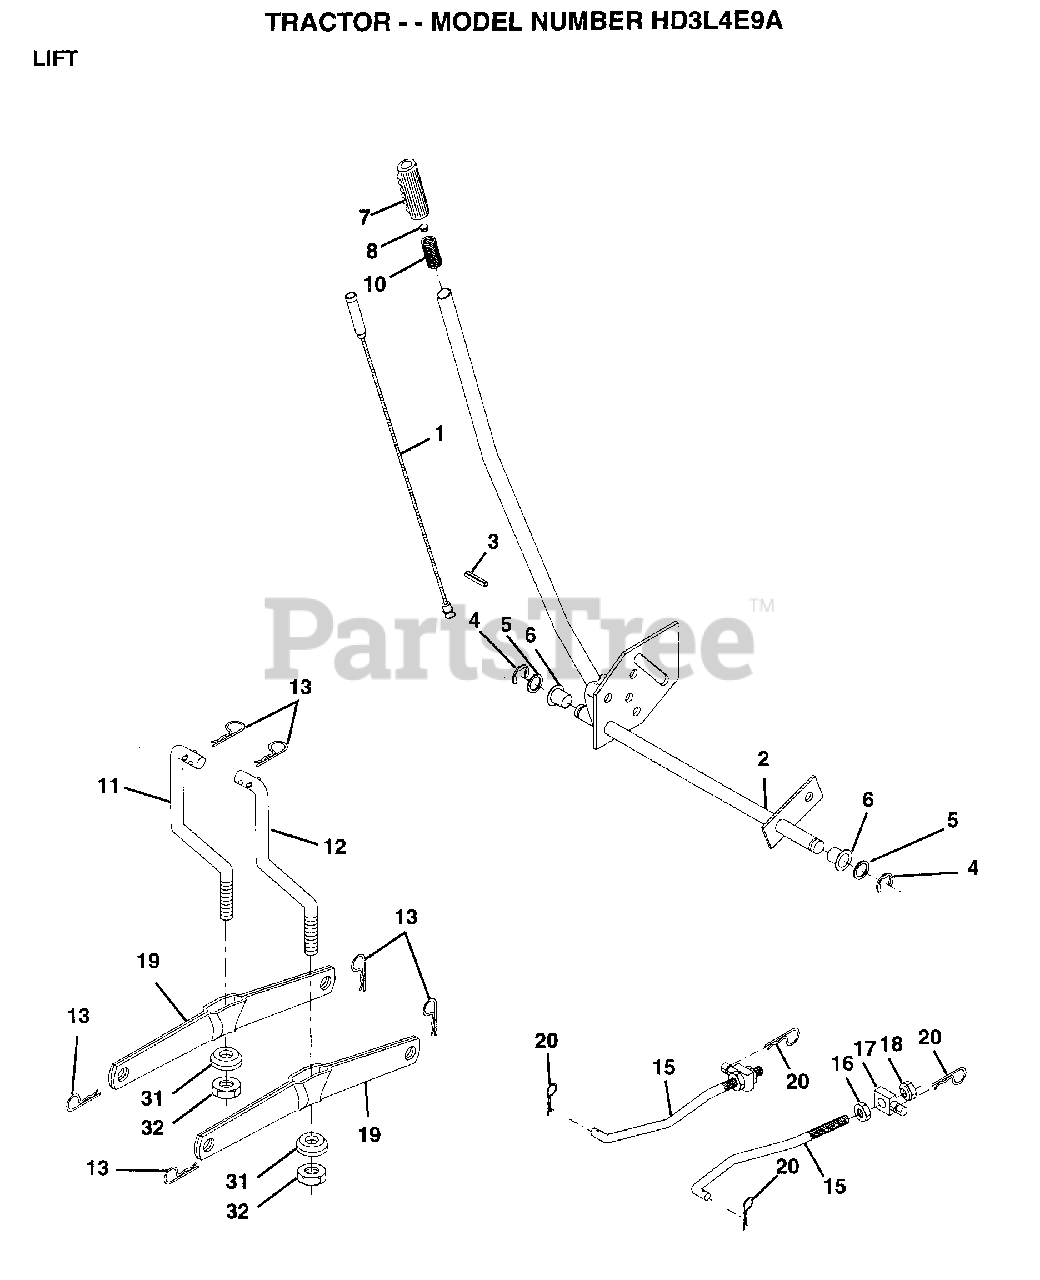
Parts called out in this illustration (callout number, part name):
1	WIRE ASM
2	HANDLE.LIFT.LH.
3	PIN GROOVE
5	WASHER
6	NYLON BEARING
7	CAP T
15	LINK.FRONT
16	NUT
17	TRUNION
18	NUT.LK.W/WSH.1/2.
19	ARM SUSP REAR
20	RETAINER.SPRING
31	BEARING PVT LH
32	NUT.CROWNLOCK.3/8
